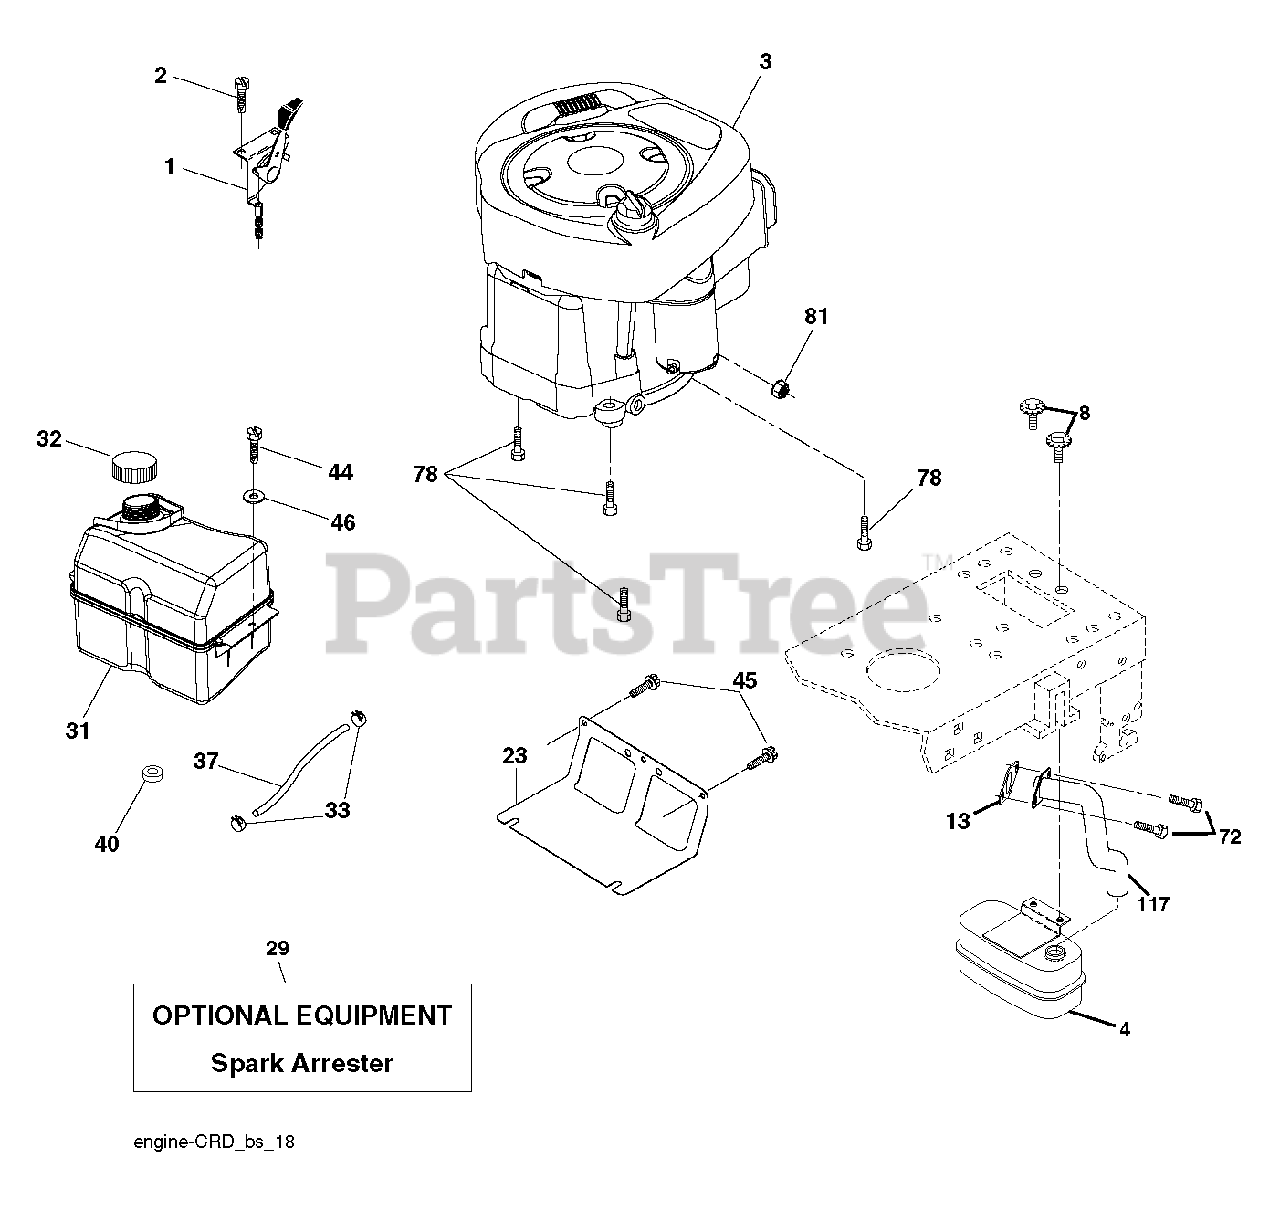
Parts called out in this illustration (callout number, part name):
1	CONTROL.TH/CK.C.
2	SCREW
4	MUFFLER.SINGLE.CYL.KOHL/B&S
8	BOLT, 5/16-18 X 1 3/4
13	REPL BY 532 27 22-93
23	SHEILD.BROWNING.DBR.GUARD
29	ARRESTER SPARK (OPTIONAL)
32	FUEL CAP
33	HOSE CLAMP
37	LINE.FUEL.20
40	BUSHING.1.375OD
44	SCREW HEXWSHR 1/4-20X3/4
45	SCREW, 3/8-16X3/4
72	SCREW.SOCKET HD.5/16-1
78	SCREW.3/8-16
81	NUT
117	EXHAUST.TUBE.B&S.
